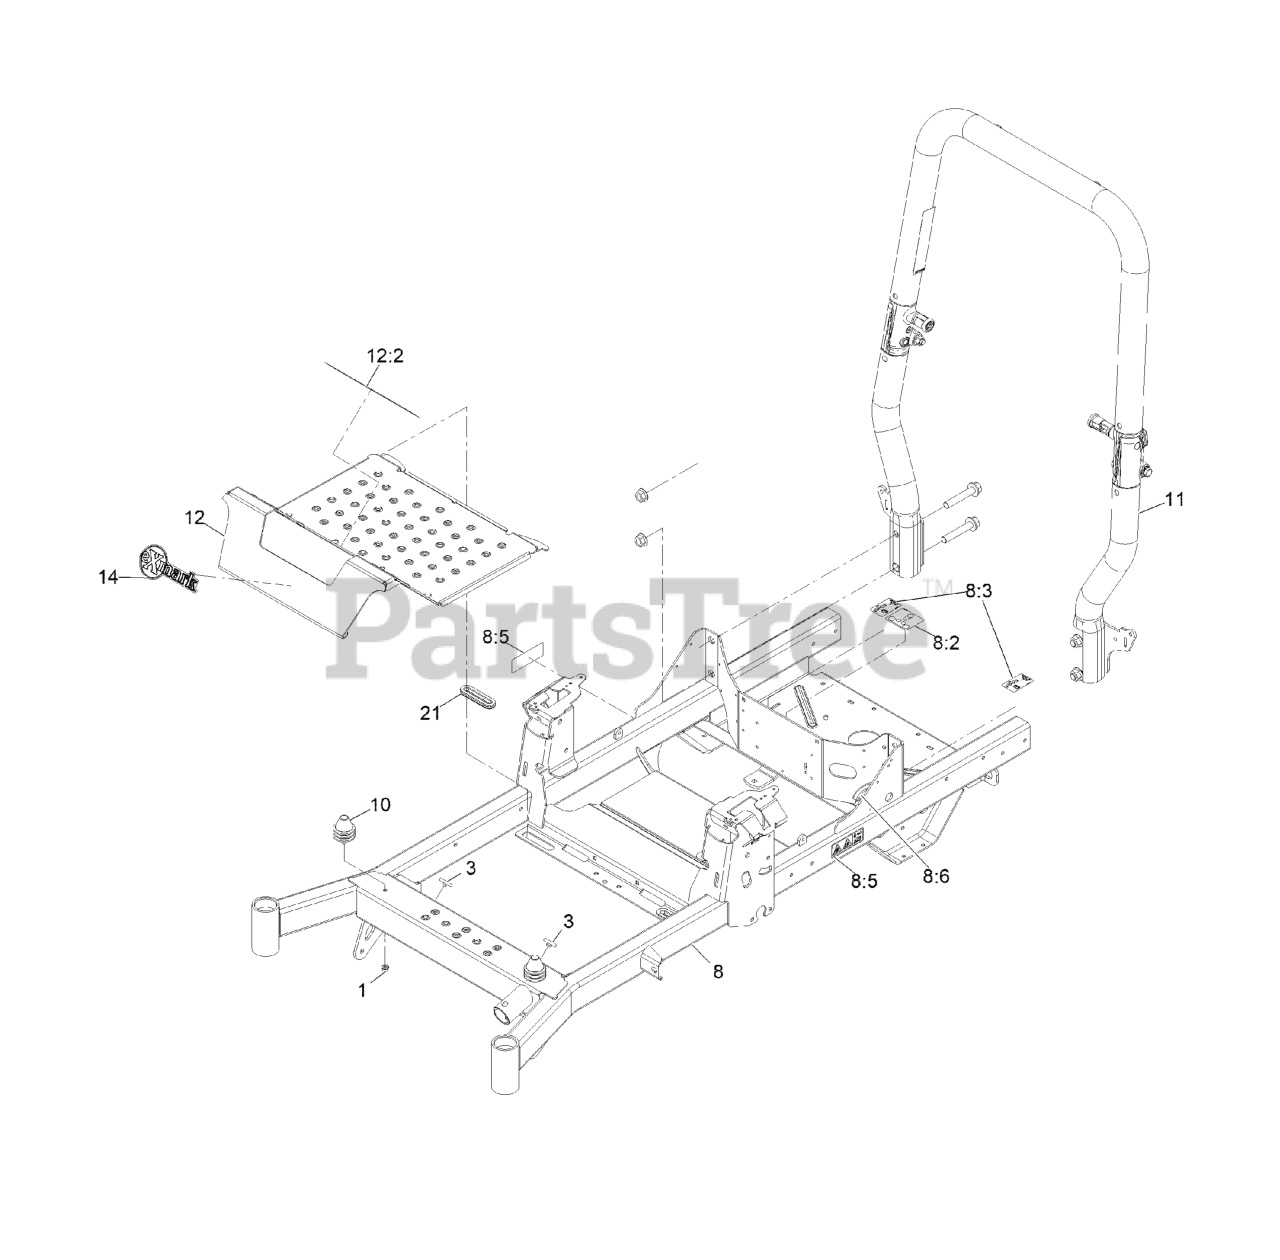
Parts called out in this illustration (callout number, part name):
1	NUT-HF, NI
3	BUMPER-PUSH-IN, RUBBER
8	FRAME ASM
8:2	DECAL-ROUTING, BELT
8:3	DECAL-RELEASE, DRIVE
8:5	DECAL-WARNING
8:6	STRIP-SEAL
10	ISOLATOR
11	ASM-ROPS TAPERED
12	PAN-FLOOR
12:2	DECAL-DANGER
14	DECAL-EXMARK LOGO
21	GROMMET-RUBBER
